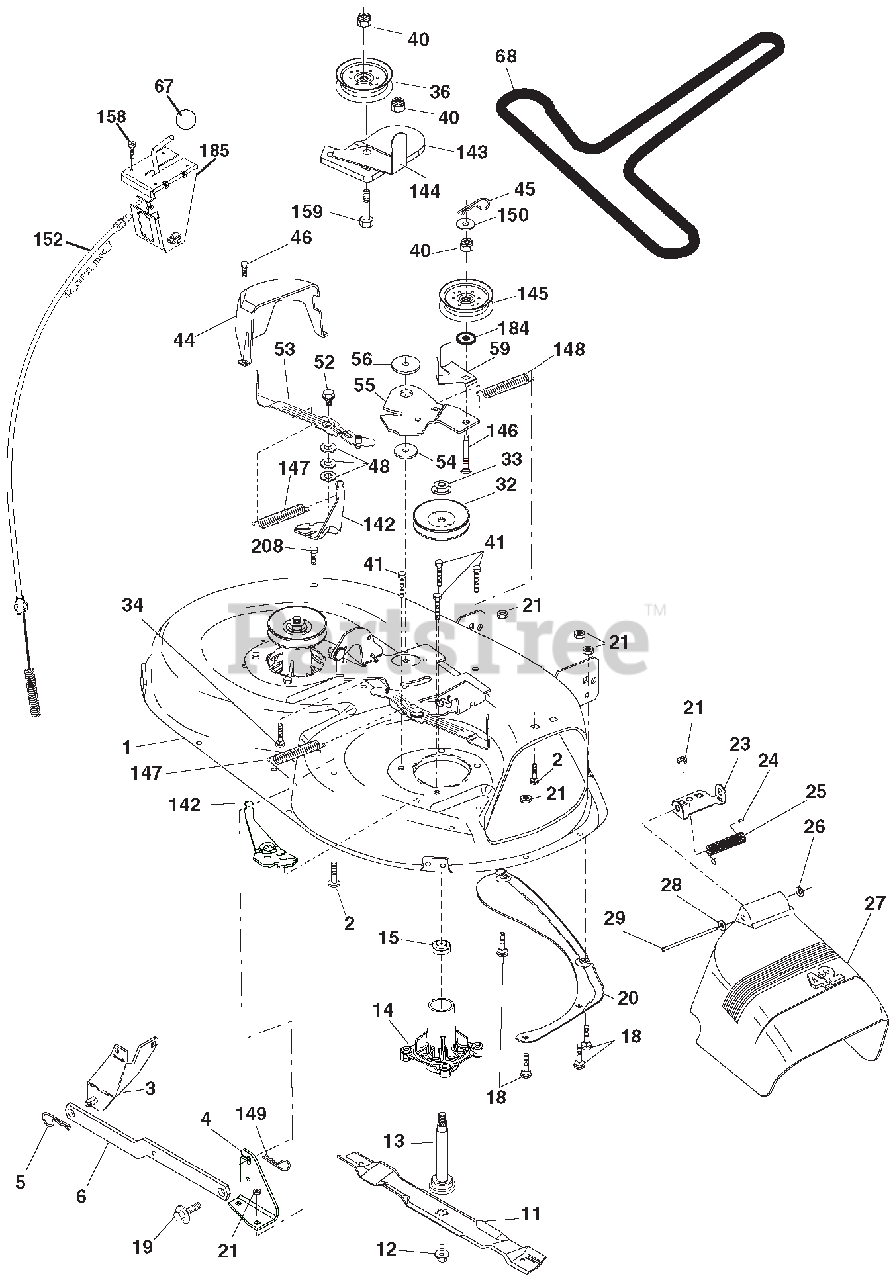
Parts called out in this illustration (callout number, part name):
1	MOWER DECK ASSEMBLY, 42"
3	Bracket Asm Fr. Sway Bar 3/42
4	Bracket Asm Deck 42" Sway Bar
5	RETAINER.SPRING
6	Bar Sway Deck
11	BLADE.MOWER.42"HI LIFT PREMIUM
12	SCREW 7/16-20 X 1
13	SHAFT ASM
14	HOUSING.MANDREL.4PT.SERVICE
15	BEARING
18	BOLT.RDHD.SQNK.5/16-18 X 5/8
19	Bolt, Shoulder
20	BAFFLE.VORTEX.42.STD/HEAVY DTY
21	Nut, Hex, Crownlock 5/16-18
23	Bracket, Deflector Mower 42"
24	CAP.SLEEVE..80X.112.BLK.MOWER
25	SPRING.TORSION
26	NUT.PUSH.PHOS.& OIL
27	SHIELD
28	Washer 11/32 x 5/8 x 16 Ga.
29	ROD.HINGE.42/46"
32	MANDREL.PULLEYS.42,44,50
32	MANDREL ASM
33	NUT.FLANGE.LOCK.TOP
34	BOLT.CARR.SH.3/8-16X1-1/2.GR5
36	PULLEY, IDLER, FLAT
40	Nut, Hex, Flangelock 3/8-16
41	HEX HEAD BOLT
44	Guard, Mandrel, LH
45	RETAINER SPRING
46	SCREW.THD.ROLL.1/4-20 X 5/8
48	Washer, Hardened
52	Bolt, Shoulder 5/16-18 unc
53	Arm Assembly, Pad, Brake
54	WASHER.FLAT.HARDENED
55	Arm, Idler
59	GUARD.TUV.IDLER
67	Knob Round
68	V-Belt, 42" Mower
142	Anchor Spring Brake Mower
143	Bracket Arm Idler 42"
144	KEEPER.BELT
145	PULLEY IDLER FLAT
146	Bolt Carriage Idler
147	Spring Extension
148	Spring Return Idler
149	Retainer Spring Yellow
150	WASHER.9/32 X 3/4 X 10 GA.
152	Clutch Cable 42"
158	Screw 1/4-20 x 1/2
159	Bolt Rdhd Sqn 3/8-16 unc x 1-3
184	Washer 13/32 x 7/8 x 10 Ga.
185	Head Asm Cable Clutch\
208	SCREW.THDROL.3/8-16X1/2.TYT.BL
209	REPLACEMENT MOWER
